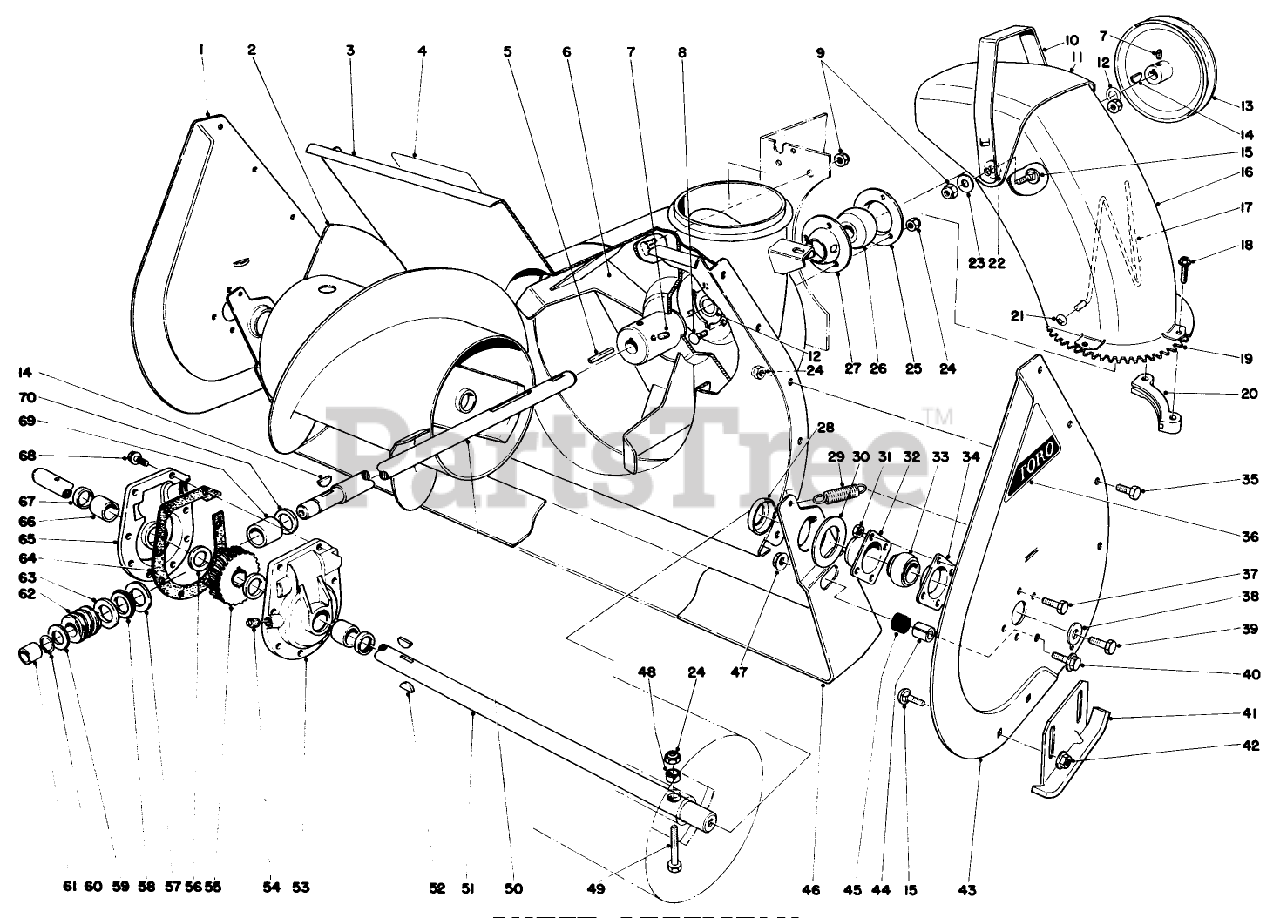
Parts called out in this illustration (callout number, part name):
1	Side Plate Right
2	Auger Right
3	AUGER HSG WA RO
4	Decal-Warning
6	IMPELLER WA RO
7	SCREW-SET, SQH
8	BOLT-CARR
9	NUT-LOCK, CONE
10	DEFLECTOR HANDLE B
11	Chute Deflector
12	WASHER
13	IMPELLER PULLEY
14	KEY-WOODRUFF
15	SCREW-CARR
16	Chute
17	WIRE-CHUTE
18	SPECIAL SCREW
19	Chute Swivel Gear
20	CHUTE RETAINER
21	NUT-PUSH
22	WASHER-RUBBER
23	WASHER-BELLEVILLE
24	NUT-LOCK, NI
25	FLANGE-CUP, BEARING
26	Ball Bearing
27	FLANGE-CUP, BEARING
28	Positioner-Scraper
29	SPRING-TENSION
30	SCRAPER BLADE SPACER
31	NUT-LOCK, CONE
32	BEARING-FLANGE, FRONT
33	BEARING
34	BEARING-FLANGE, REAR
35	SCREW-HH
36	AUGER SIDE PLT DECAL
37	SCREW-HH
38	WASHER
39	SCREW-HH
40	SCREW-HHF
41	AUGER SKID WA R
42	NUT-HHF, WHIZ
43	Sideplate Auger Left
44	SCRAPER STOP SPACER
45	SCRAPER STOP CUSHION
46	24 SCRAPER BLD
47	NUT-HF
48	SPACER-HUB, AUGER
49	Auger Bolt
50	Shaft Impeller
51	24 AUGER SHAFT
52	KEY-WOODRUFF
53	Gear Case (Inch. Ref. #66 & 67)
54	PLUG-PIPE, SQH
55	GEAR-WORM, 27T
56	WASHER-THRUST
57	WASHER-THRUST
58	BEARING-THRUST
59	WASHER-THRUST
60	Ring-Snap
61	BUSHING
63	THRUST-WASHER
64	asket
65	Gear Case (Incl. Ref. #66 & 67)
66	BUSHING
67	SEAL-OIL
68	SCREW-TAPTITE
69	BUSHING-SPECIAL
70	RING-QUAD
